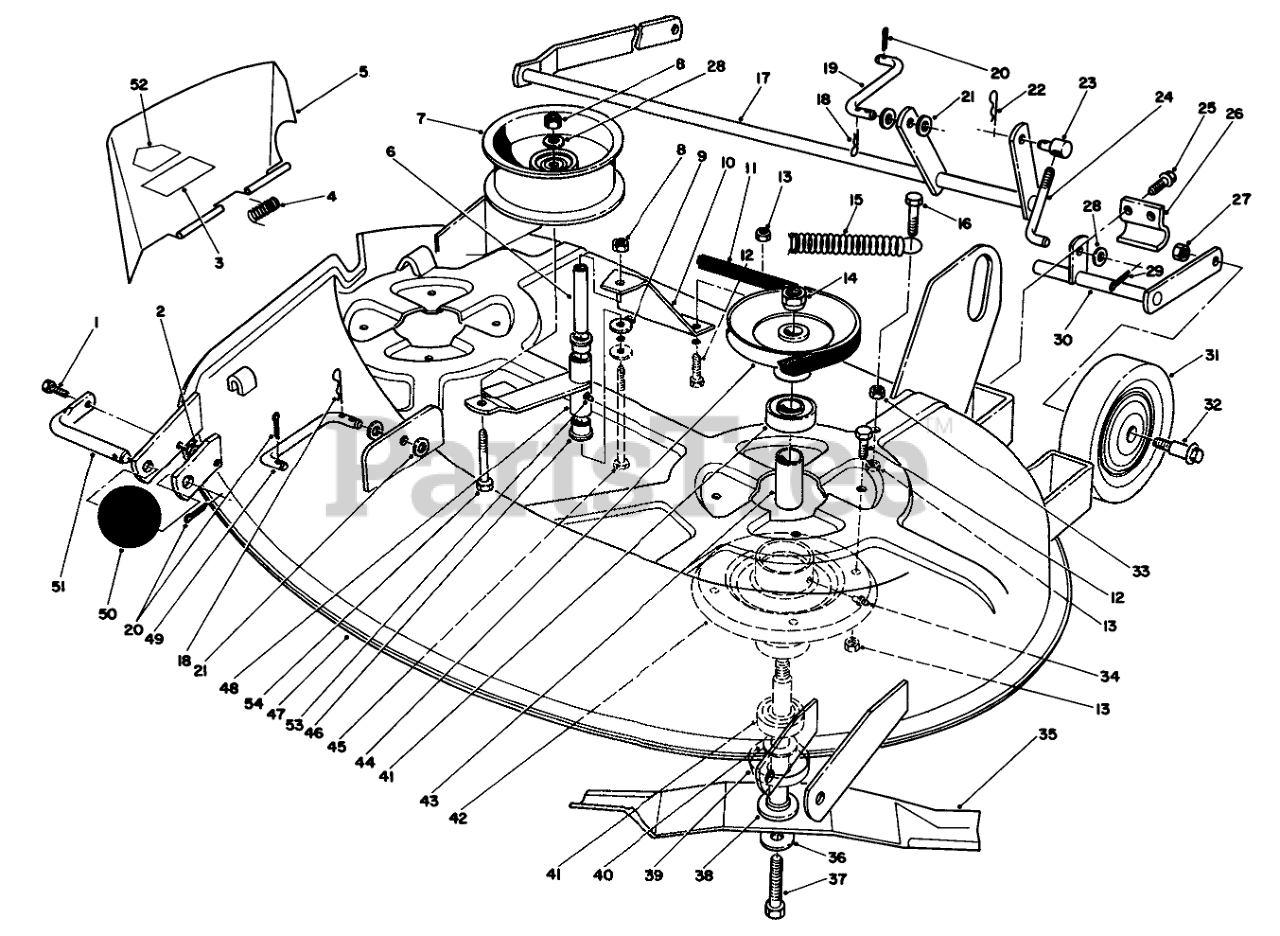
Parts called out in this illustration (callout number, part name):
1	SCREW-HH
2	NUT-LOCK, NI
3	DECAL-DANGER, THROWN OBJECT
4	SPRING-TORSION
5	Deflector
6	SPACER
7	Pulley-Idler
8	NUT-LOCK, NI
9	WASHER
10	Brace
11	V-BELT
12	SCREW-HH
13	NUT-LOCK, NI
14	Nut
15	SPRING-EXTENSION
16	SCREW-HH
17	Shaft-R.H.
18	Hairpin
19	LINK-REAR
20	PIN-COTTER
21	WASHER-FLAT
22	Hairpin
23	TRUNNION
24	ROD-LIFT
25	Bolt
26	Camp
27	NUT-HEX
28	WASHER-FLAT
29	PIN-COTTER
30	Shaft-L.H.
31	WHEEL
32	BOLT-SHOULDER
33	NUT-HEX
34	ZERK FITTING
35	Blade
36	WASHER
37	SCREW-HH
38	SHAFT-SPINDLE
39	SHIELD-BEARING
40	SPACER-HARDNED
41	BEARING-BALL
42	Housing-Spindle
43	SPACER
44	Pulley-Spindle
45	SCREW-HH
46	BUSHING
47	Deck-Cutting Unit
48	Arm-Idler
49	LINK-FRONT
50	ROLLER
51	SHAFT-ROLLER
52	DECAL-DANGER
53	FITTING-GREASE
54	SCREW-HH
